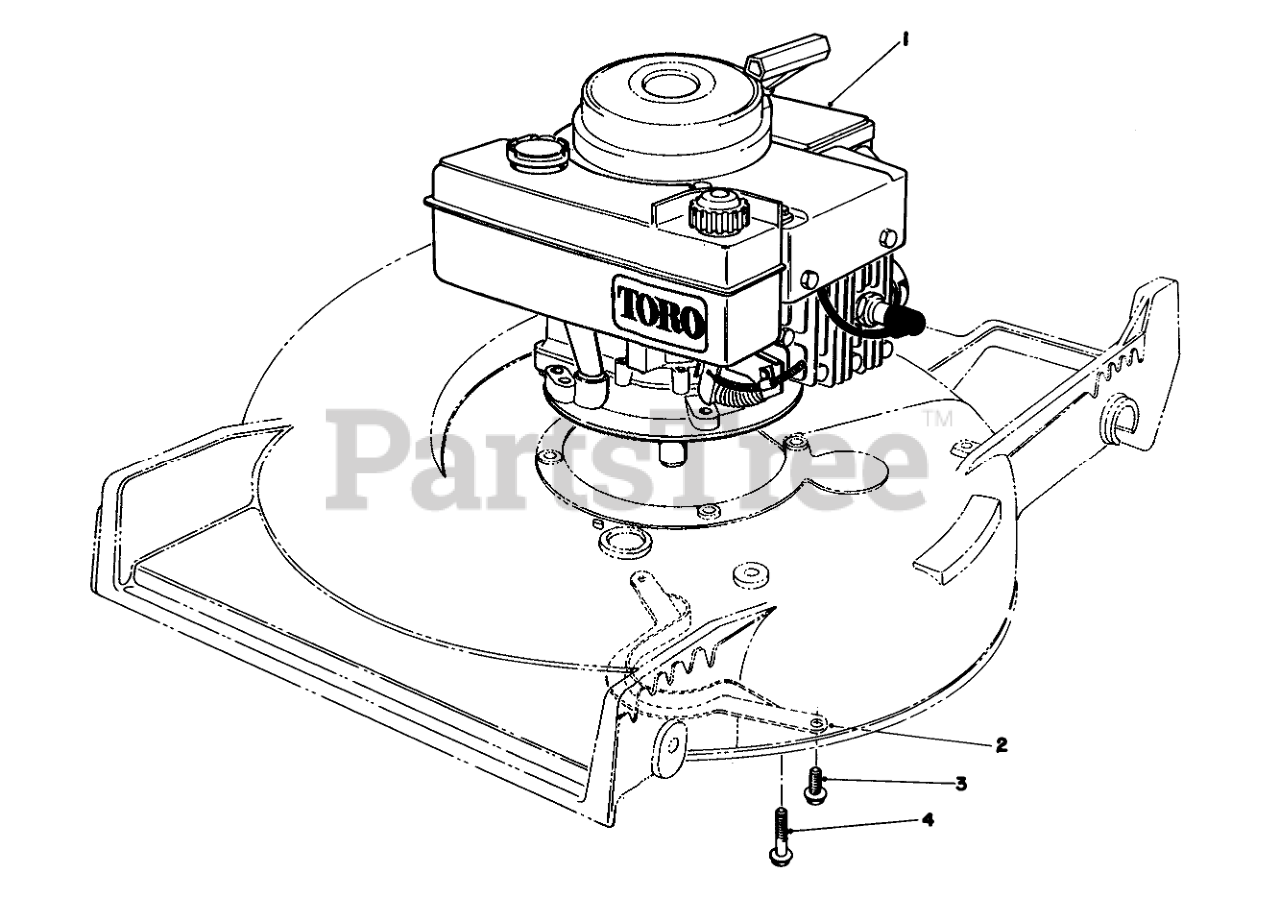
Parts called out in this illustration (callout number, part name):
2	BBC BELT GUIDE
3	SCREW-HWHTF
4	3/8-16 X 2 CAPSCREW
